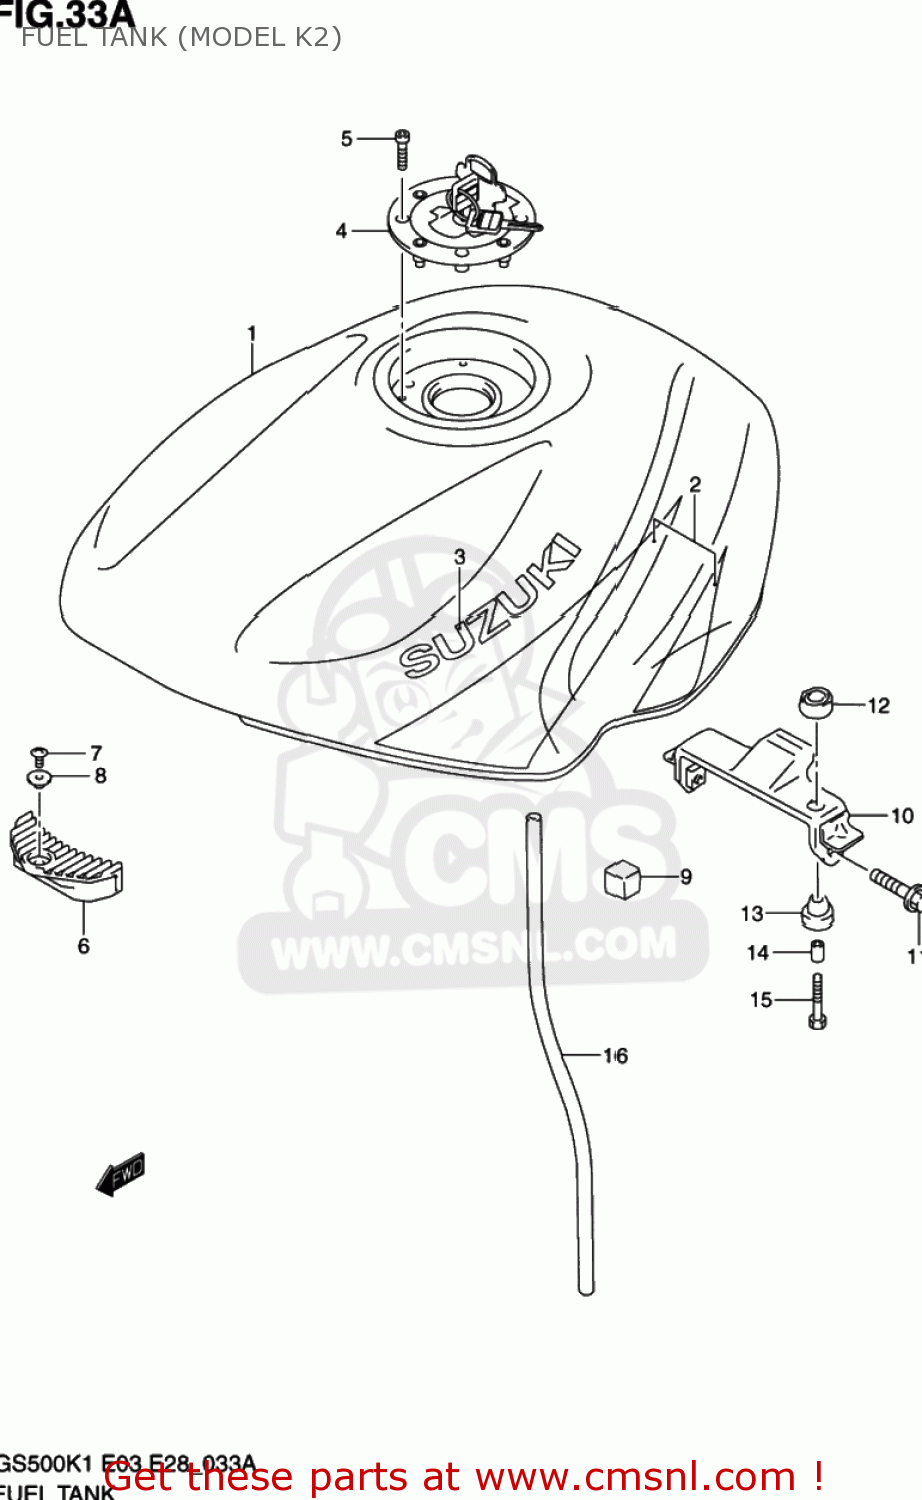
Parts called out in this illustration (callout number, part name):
1	TANK ASSY,FUEL(BLACK)
2	TAPE SET,FUEL TANK
3	EMBLEM(WHITE)
4	CAP SET,FUEL TANK
5	BOLT(5X20)
6	CUSHION,FUEL TANK FR
7	SCREW
8	WASHER
9	CUSHION,FUEL TANK SIDE
10	BRACKET,FUEL TANK RR
11	BOLT
12	CUSHION
13	CUSHION
14	SPACER(6.5X9X18)
15	BOLT(6X30)
16	HOSE,WATER DRAIN
